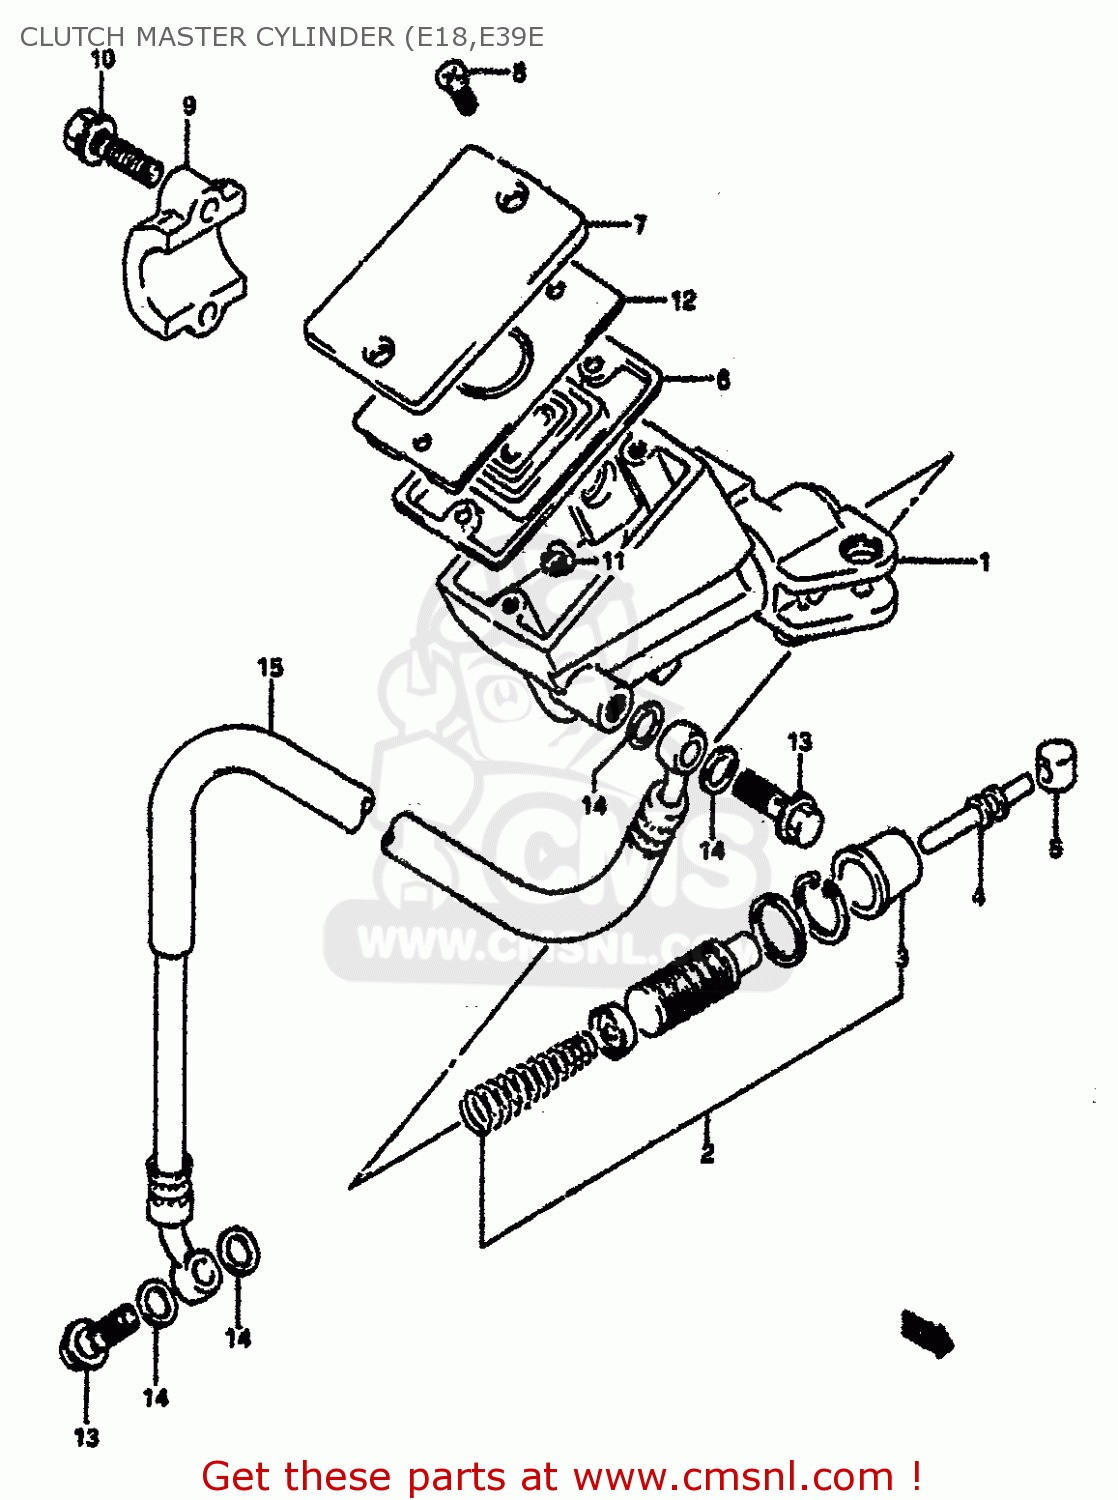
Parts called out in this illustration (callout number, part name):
1	CYLINDER ASSEMBLY,CLUTCH MASTER
2	PISTON & CUP SET
3	BOOT
4	ROD,PUSH
5	BUSH
6	7
7	CAP
8	SCREW
9	HOLDER
10	BOLT
11	PROTECTOR
12	PLATE,DIAPHRAGM
13	BOLT UNION
14	WASHER(10X15X1.5)
15	HOSE COMP,CLUTCH
